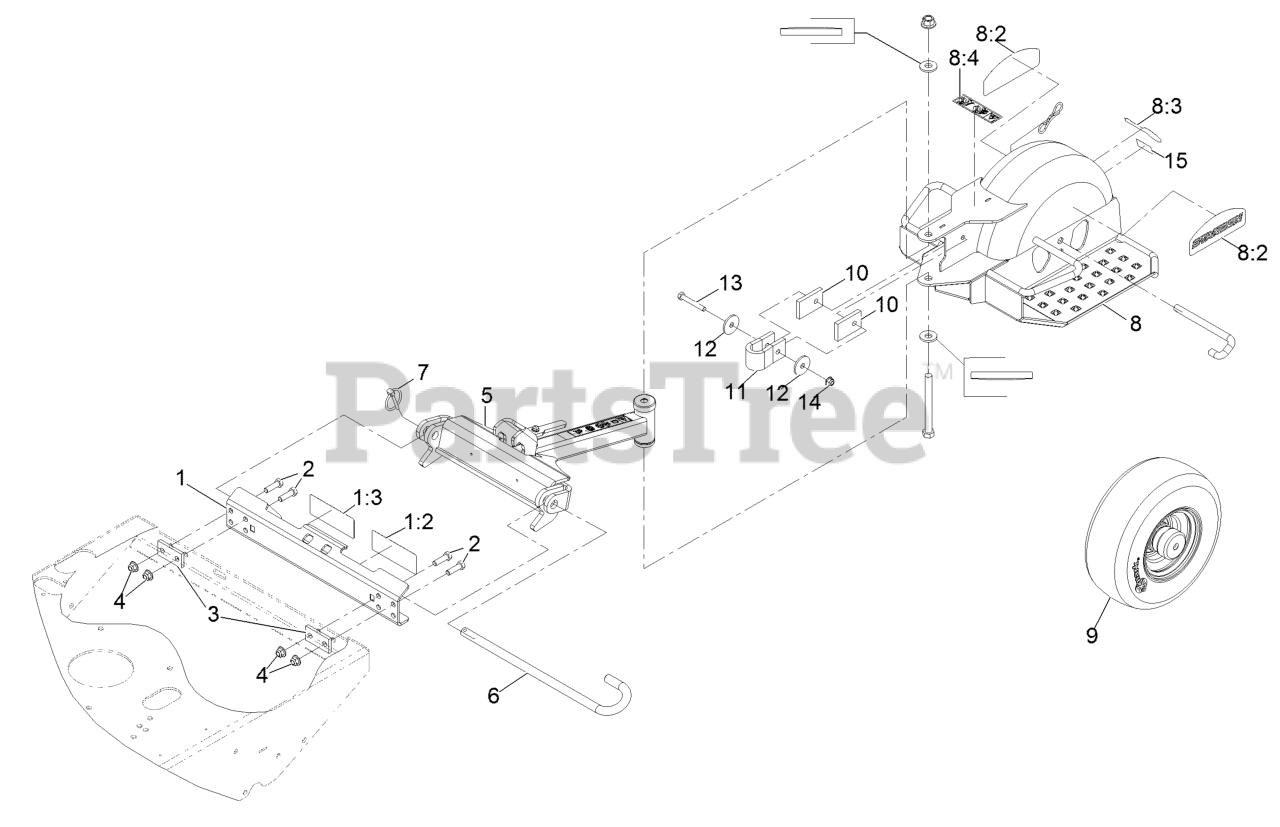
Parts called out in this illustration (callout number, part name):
1	ASM, MOUNT PLATE
1:2	DECAL-BELT DRIVE WARNING
1:3	DECAL-WARNING, SULKY
2	SCREW-HH
3	PLATE,BACK-UP (PLATED)
4	NUT-HF, NI
5	ASM, DRAW BAR
6	PIN, PIVOT
7	PIN-LYNCH
8	ASM-SULKY FRAME W/ DECALS
8:2	DECAL, STANDON
8:3	DECAL, EXMARK
8:4	DECAL-WARNING HAND PINCH
9	ASM, WHEEL AND BEARINGS
10	PAD,STOP
11	STOP, ROTATION
13	SCREW-HH
14	NUT-HF, NI
15	Decal-Patent
